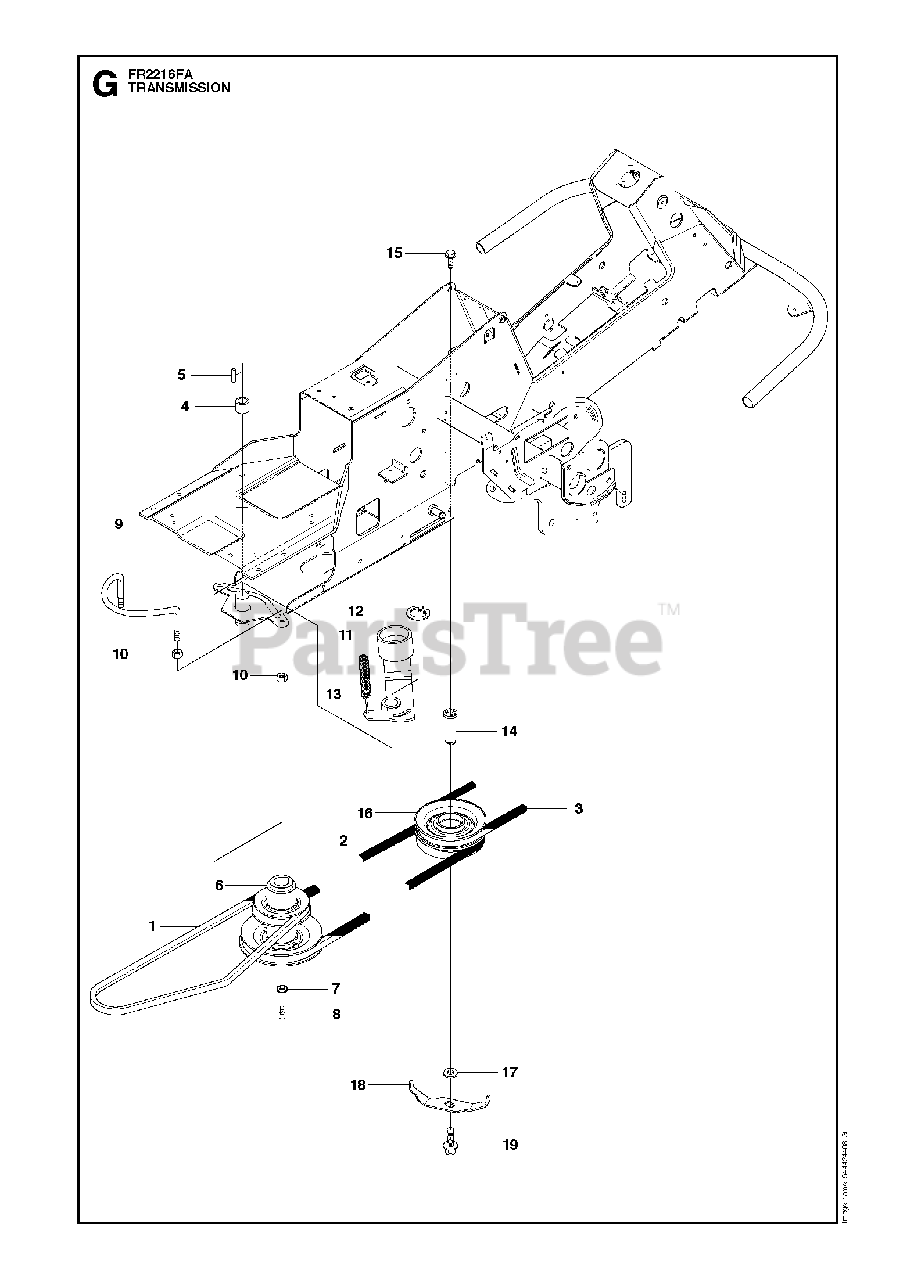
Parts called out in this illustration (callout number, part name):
1	BELT
2	WASHER **
5	FAN
6	RETAINING RING **
8	CLAMP
9	CLIP
10	PLUG
11	MAGNET
12	MAGNET HOLDER
13	SEALING
14	CONTROL LEVER
15	PIN
16	ARM
17	PIN
18	PIN
19	ARM
